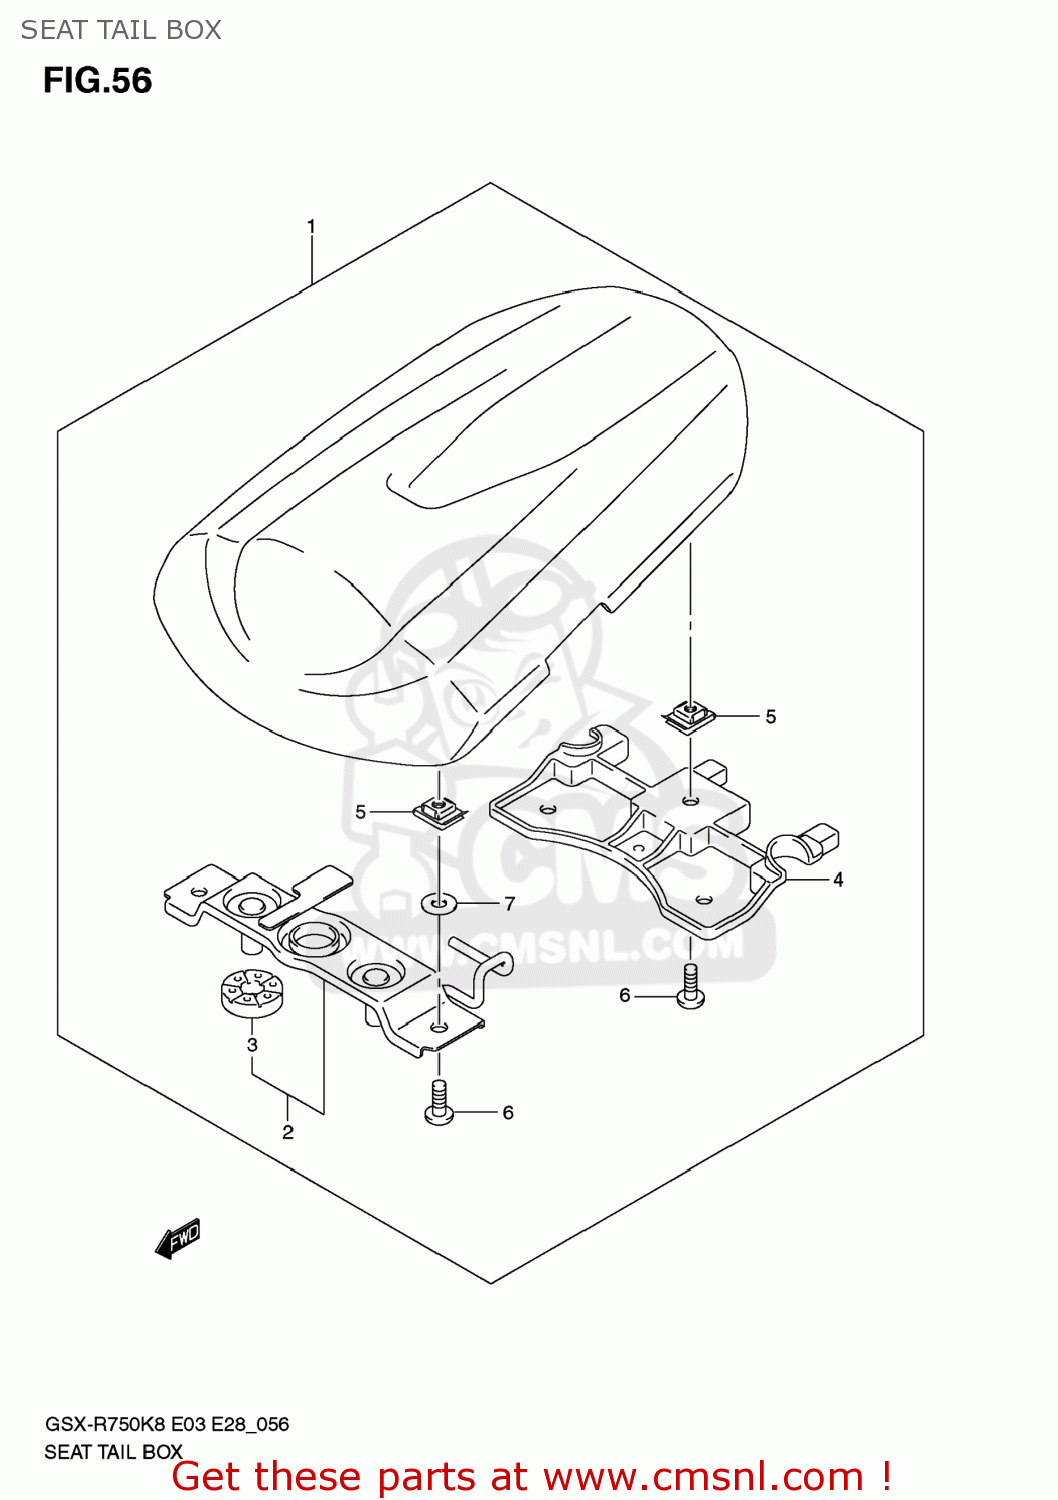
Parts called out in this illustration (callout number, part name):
1	BOX,SEAT TAIL
2	STRIKER,SEAT LOCK
3	CUSHION
4	BOTTOM,SEAT TAIL BOX
5	NUT
6	SCREW
7	WASHER(6.5X20X1.2)
